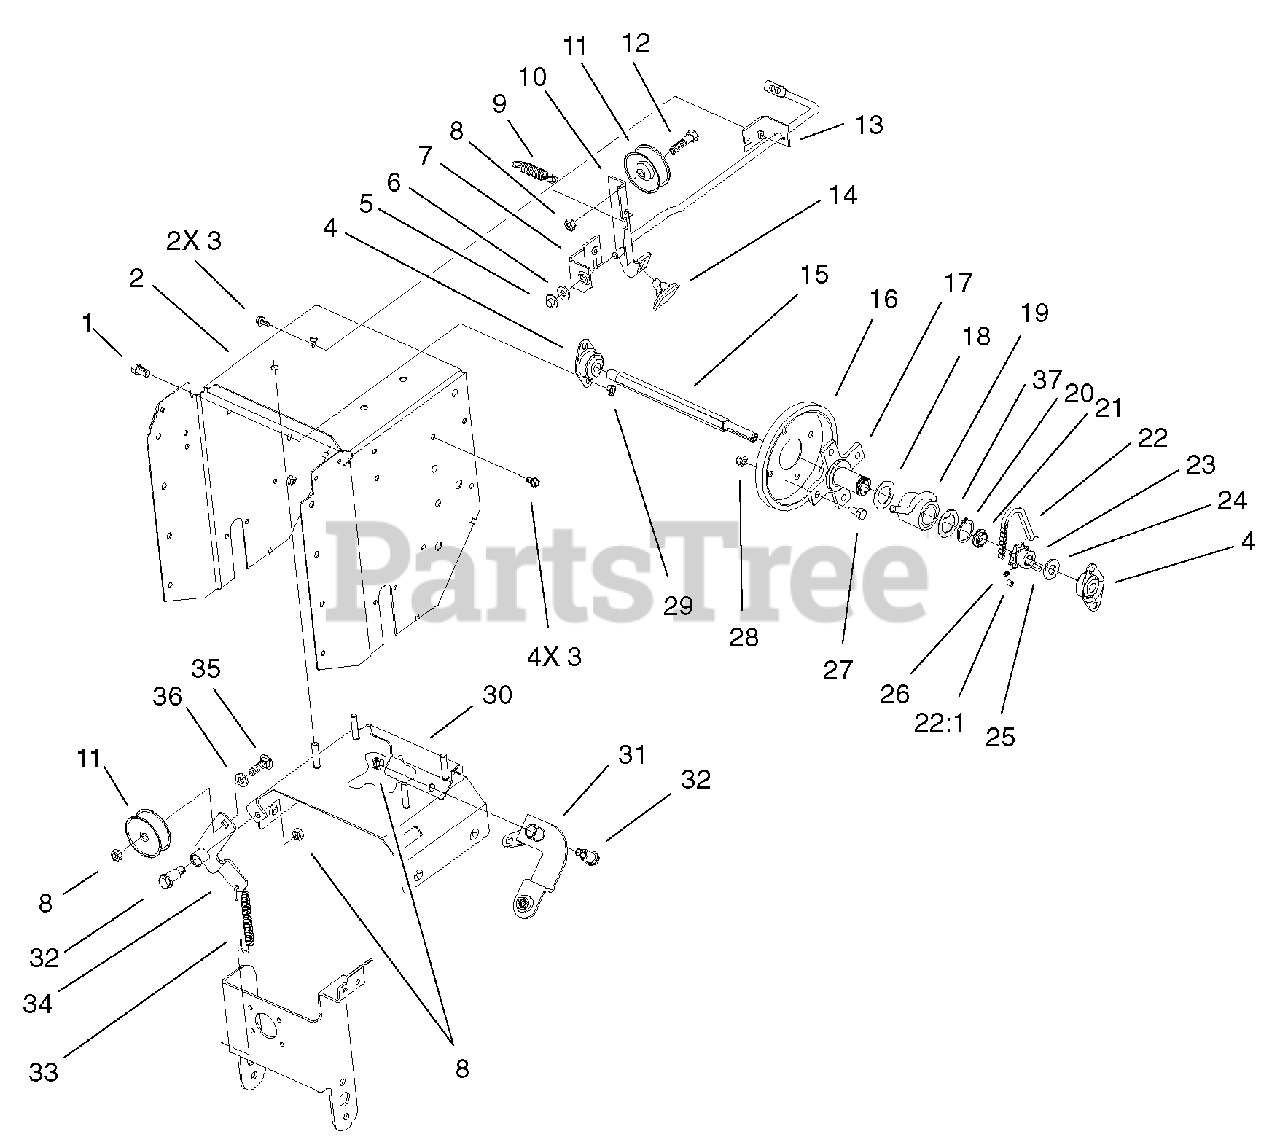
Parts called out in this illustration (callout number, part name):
1	SCREW-HH
2	FRAME-TRACTION
3	SCREW-HWH
4	BEARING-TRIANGLE
5	RETAINER-PUSH ON
6	WASHER-FLAT
7	MOUNTING-CLUTCH ROD BRACKET
8	NUT-LOCK, NI
10	CLUTCH-AUGER
11	PULLEY-IDLER
12	SCREW-HH
13	MOUNTING-REAR CLUTCH ROD
14	PAD-BRAKE
15	SHAFT-HEX
16	FRICTION WHEEL
17	HUB-TRACTION DISC
18	WASHER-THRUST
19	SLIDER RING ASM
20	RING-RETAINING
22	ROLLER-CHAIN
22:1	LINK-CONNECTING (only on: 38078)
23	SPROCKET
24	WASHER-THRUST
25	KEY-SQUARE
26	SCREW-HSH
27	SCREW-HH
28	NUT-LOCK, NI
29	NUT-LOCK, NI
31	SHIFT ARM ASM
32	BOLT-SHOULDER
33	SPRING-EXTENSION IDLER
34	BRACKET-IDLER HUB
35	SCREW-CARR
37	WASHER-THRUST
